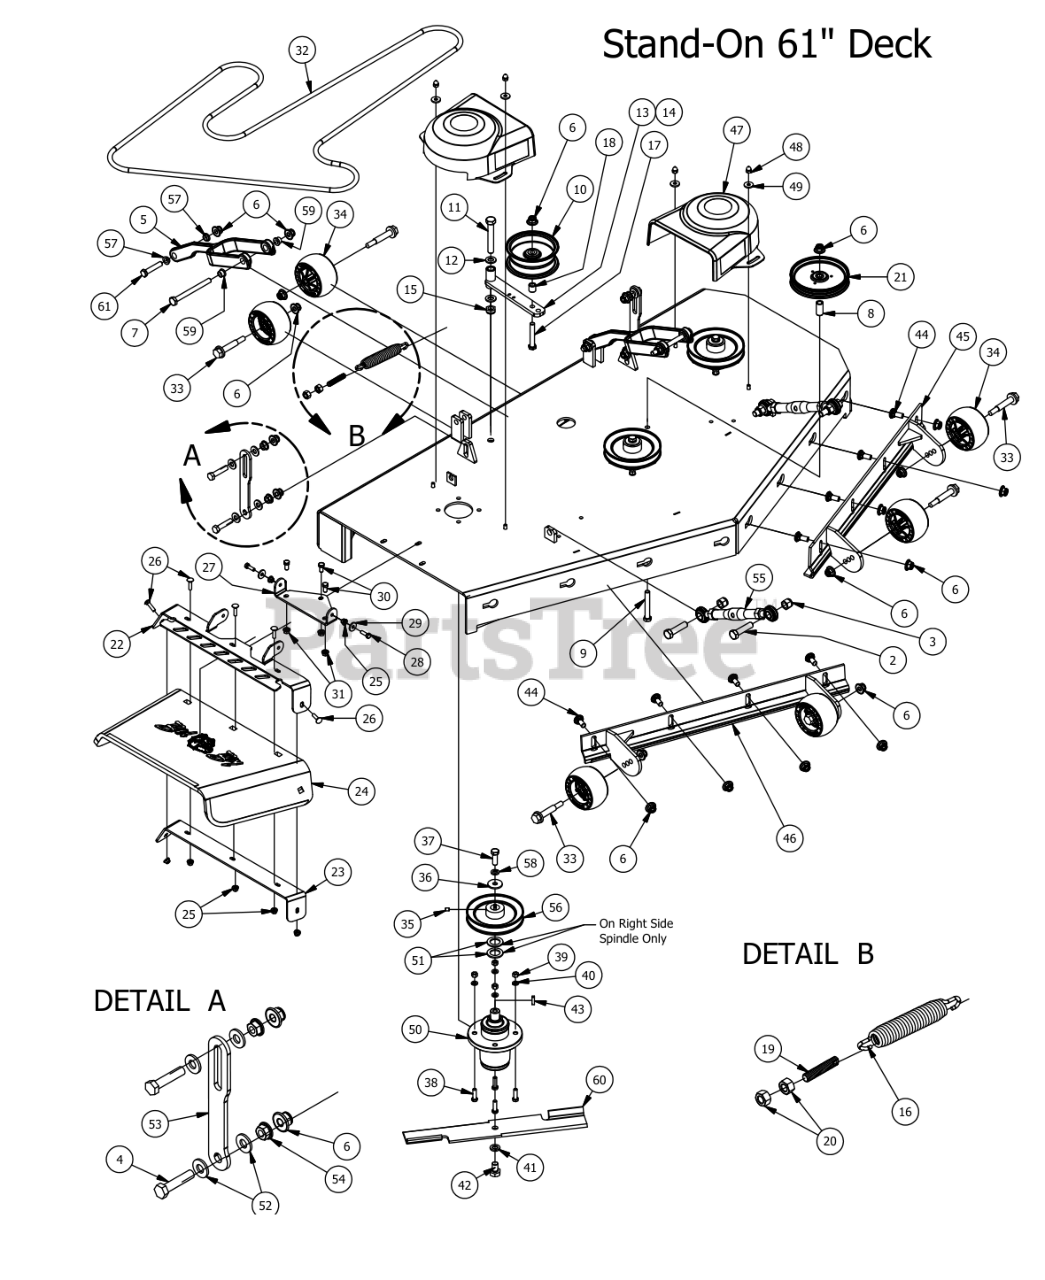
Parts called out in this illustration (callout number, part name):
1	61" 2015 Stand-On Deck (Welded Assembly)
2	5/8" x 2 1/2" Hex Bolt
3	5/8 Std NC Nylock Nut
4	1/2-13X 2-1/4 GR Hex Bolts
5	Deck Arm Assembly
6	1/2-13 Nylon Flange Nut
7	1/2" x 5 1/2" Bolt
8	.502 ID X.750 OD X 1.500 Long Spacer
9	1/2 x 3 1/2 Flange Bolt Grade 8
10	5 3/4" Deck Idler Pulley
11	5/8" x 4" Hex Bolt
12	.630 ID Plastic Washer
13	Deck Idler Arm
14	Deck Idler Arm Assembly (Includes 6,10,13,17,18)
15	5/8" Nylock (1/2 Jam)
16	2009 Deck/Pump Idler Spring
17	1/2-13 x GR 5 Hex Bolt Zinc
18	Spacer 3/4 OD x 1/2 ID x 3\4 Length
19	All Thread-Pump Idler Tensioner
20	1/2" Hex Nut
21	5-3/4 Idler Pulley-Don Dye
22	60" Discharge Chute Upper Hanger
23	60" Discharge Lower Bracket
24	Rubber Discharge Chute
25	5/16" Nylock Flange Nut Zinc
26	5/16" x 1 1/4" Carriage Bolt
27	Discharge Chute Hanger (deck mounted)
28	5/16" x 1" Bolt
29	.360 ID Plastic Washer
30	3/8" x 3/4" Hex Bolt
31	3/8" Flange Nut
32	54" MZ Magnum Belt - B138
33	Deck Wheel Bolt
34	Anti-Scalp Rollers
35	5/16 Set Screw
36	1/2 Belleville Washer
37	1/2"-20 x 1 1/2 - Grade 5 Fine Thread Bolt
38	3/8" x 1 1/4" Hex Bolt
39	3/8-16 Hex Nuts Zinc
40	3/8" Lock Washer
41	5/8" Lock Washer
42	5/8" x 1 1/2" Grade 8 Hex Bolt (Fine)
43	1/4" x 1" Key
44	1/2" x 1 1/4 Carriage Bolt
45	61 Deck Adustable Front (Left)
46	61 Deck Adustable Front (Right)
47	Pulley Cover
48	Acorn nut-pulley Cover
49	.360 ID Plastic Washer-Black
50	OUTLAW SPINDLE ASSEMBLY
51	1 1/8" Flat Spacer
52	.505 Nylon Spacer
53	Longer deck hanger
54	1/2" Flange Nut
55	Turnbuckle
56	6 1/4" Drive Pulley
57	Flange Bushing For Lower Deck Arm
58	1/2" Lock Washer
59	Flange Bushing For Upper Deck Arm
60	61 inch Fusion Blade
61	1/2" x 3" Hex Bolt
